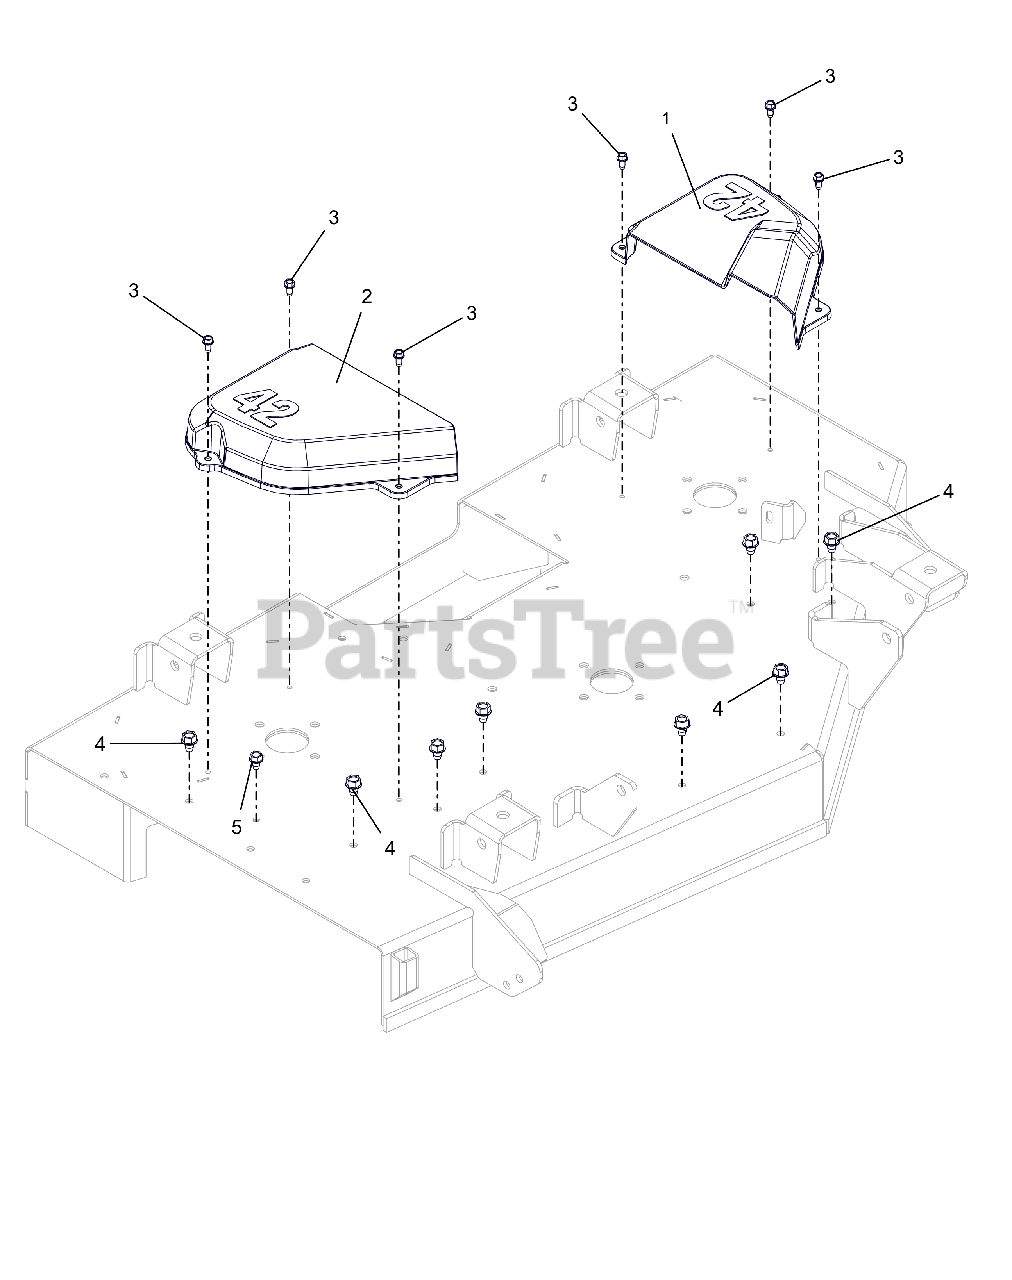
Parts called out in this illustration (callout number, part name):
1	COVER, BELT 42" LH
2	COVER, BELT 42" RH
3	SCR-TAP .25-20X.50 HWH ZCC
4	SCR,TAP .375-16X.50 HWH TR ZCC
5	SCR,TAP .312-18X.50 HWH TR ZCC
